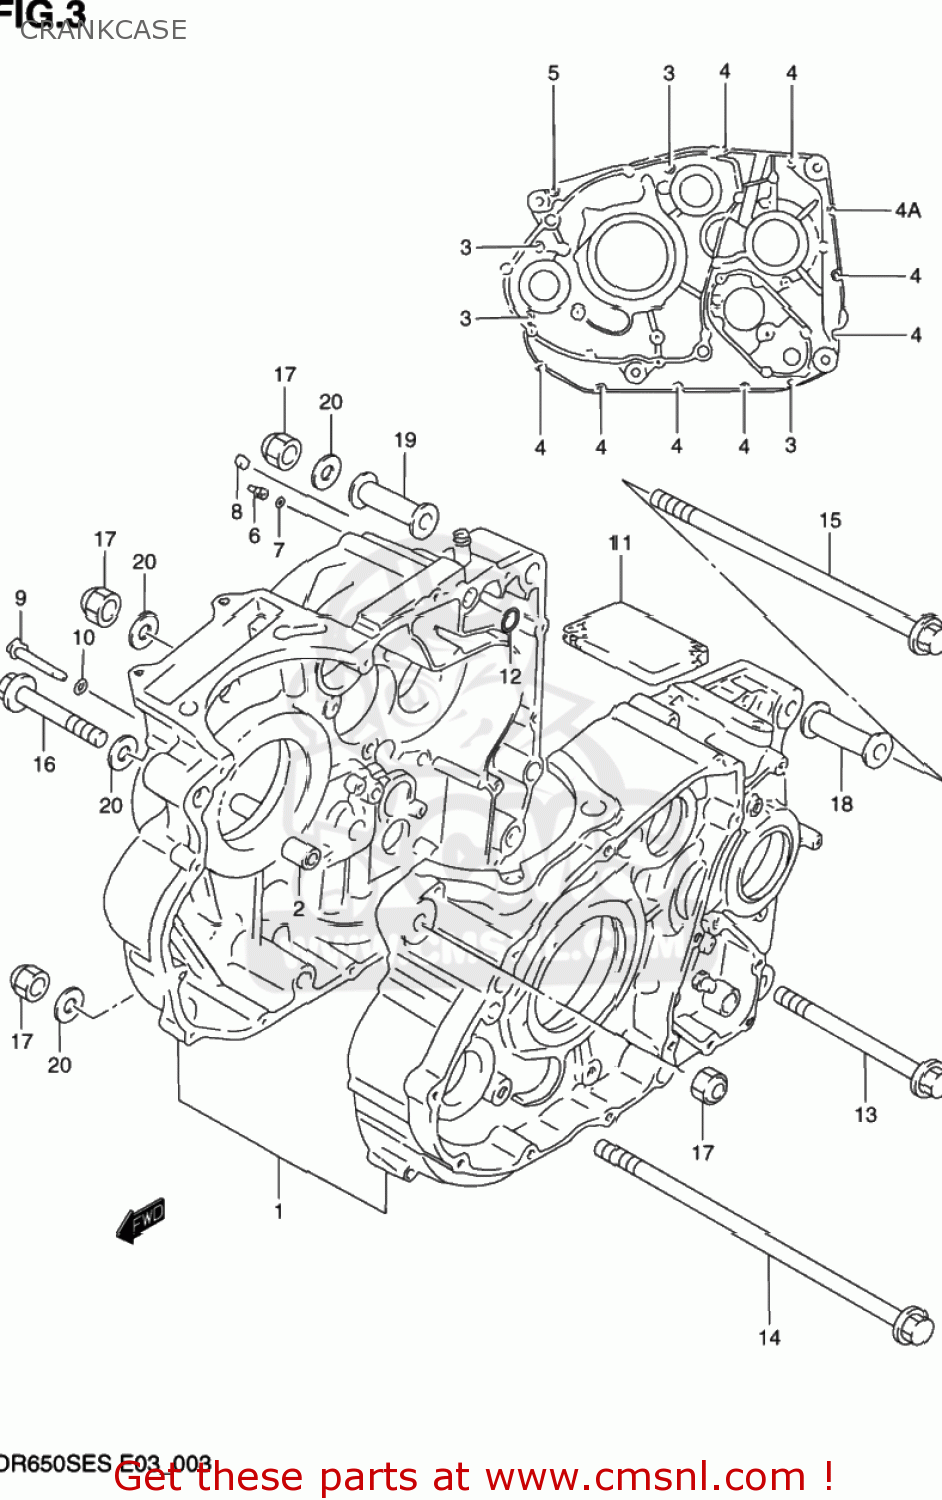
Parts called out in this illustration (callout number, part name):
1	CRANKCASE SET
2	PIN
3	BOLT
4	BOLT
4A	BOLT
5	BOLT
6	JET(12)
7	O RING(D:1.2,ID:4)
8	JET,OIL GALLERY
9	PIPE,PISTON COOLING
10	O-RING
11	SEPARATOR,OIL BREATHER
12	O-RING
13	BOLT(10X130)
14	BOLT 10X230
15	BOLT(10X235)
16	BOLT(10X80)
17	NUT
18	SPACER,ENG MTG(L:55)
19	SPACER,ENGINE MOUNT(L:65)
20	WASHER
